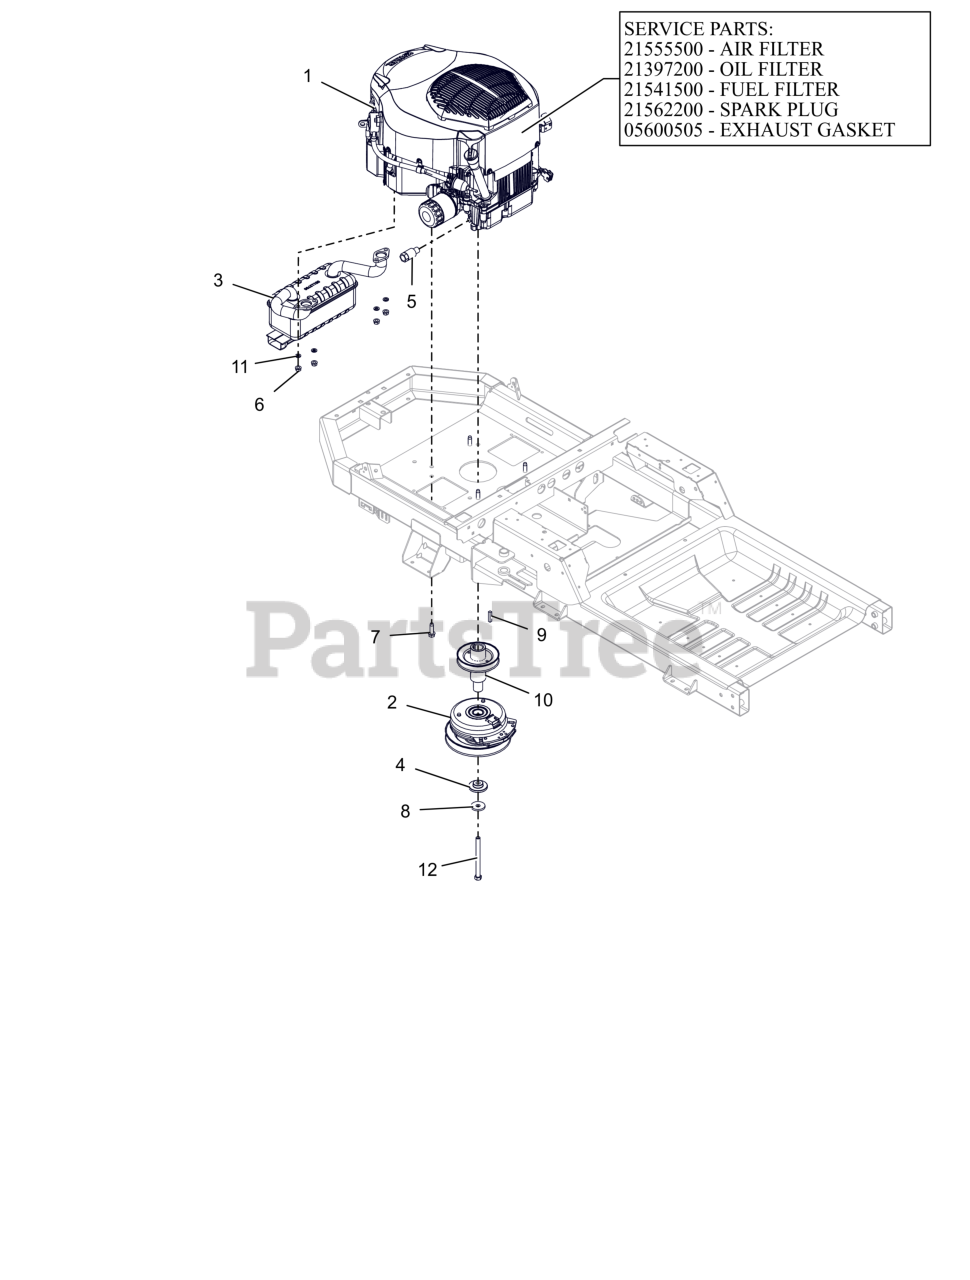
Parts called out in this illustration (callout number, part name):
1	ENGINE, KOHLER 22HP TWIN
1	AIR CLEANER, KOHLER
1	FILTER, OIL - KOH CV20
1	FILTER, FUEL
1	PLUG, SPARK (RFI)
1	GASKET, MUFFLER KOHLER TWIN
2	CLUTCH,105FTLB MONOPOLE 6.83"
3	MUFFLER, KOHLER
4	BSHG-FLG .469X1.06X.574X2.0
5	DRAIN, OIL
6	NUT-LK-TOP-FLG .312-18 GF ZCC
7	SCR,TAP .375-16X1.25HWH TR ZCC
8	WASHER, 7/16" SPRING DISK
9	KEY-SQ .25 X 1.25 X .25 SAE
10	WLDMT, DRIVE SHEAVE (LONG)
11	WSHR,LK-REG .312X.078 ZCC
12	BLT, HEX .44-20X5.00 G8 ZCC NT
